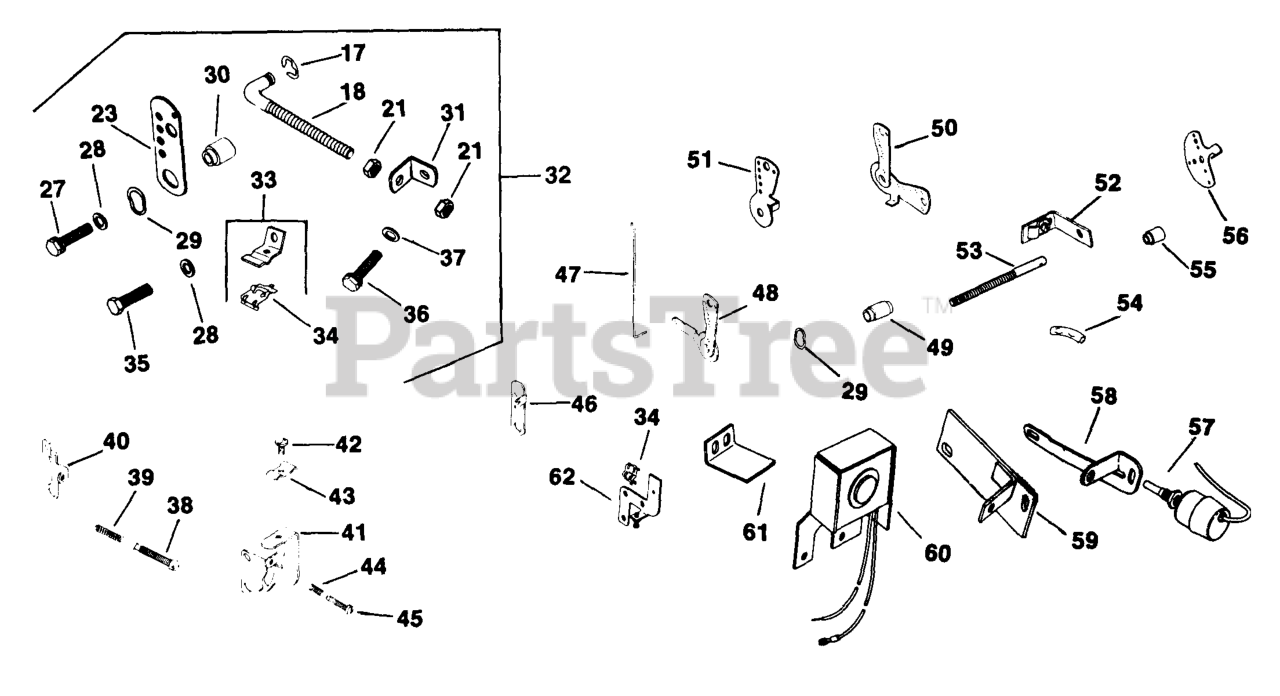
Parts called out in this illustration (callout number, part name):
17	RETAINER
23	BRACKET-DISCONTINUED
28	WASHER, FLAT 1/4" (O.D. 1/2")
29	WASHER, SPRING 11/32"
31	BRACKET, ADJUSTING SCREW - DISCONTINUED
35	SCREW, SEMS 1/4-20-1/2"
